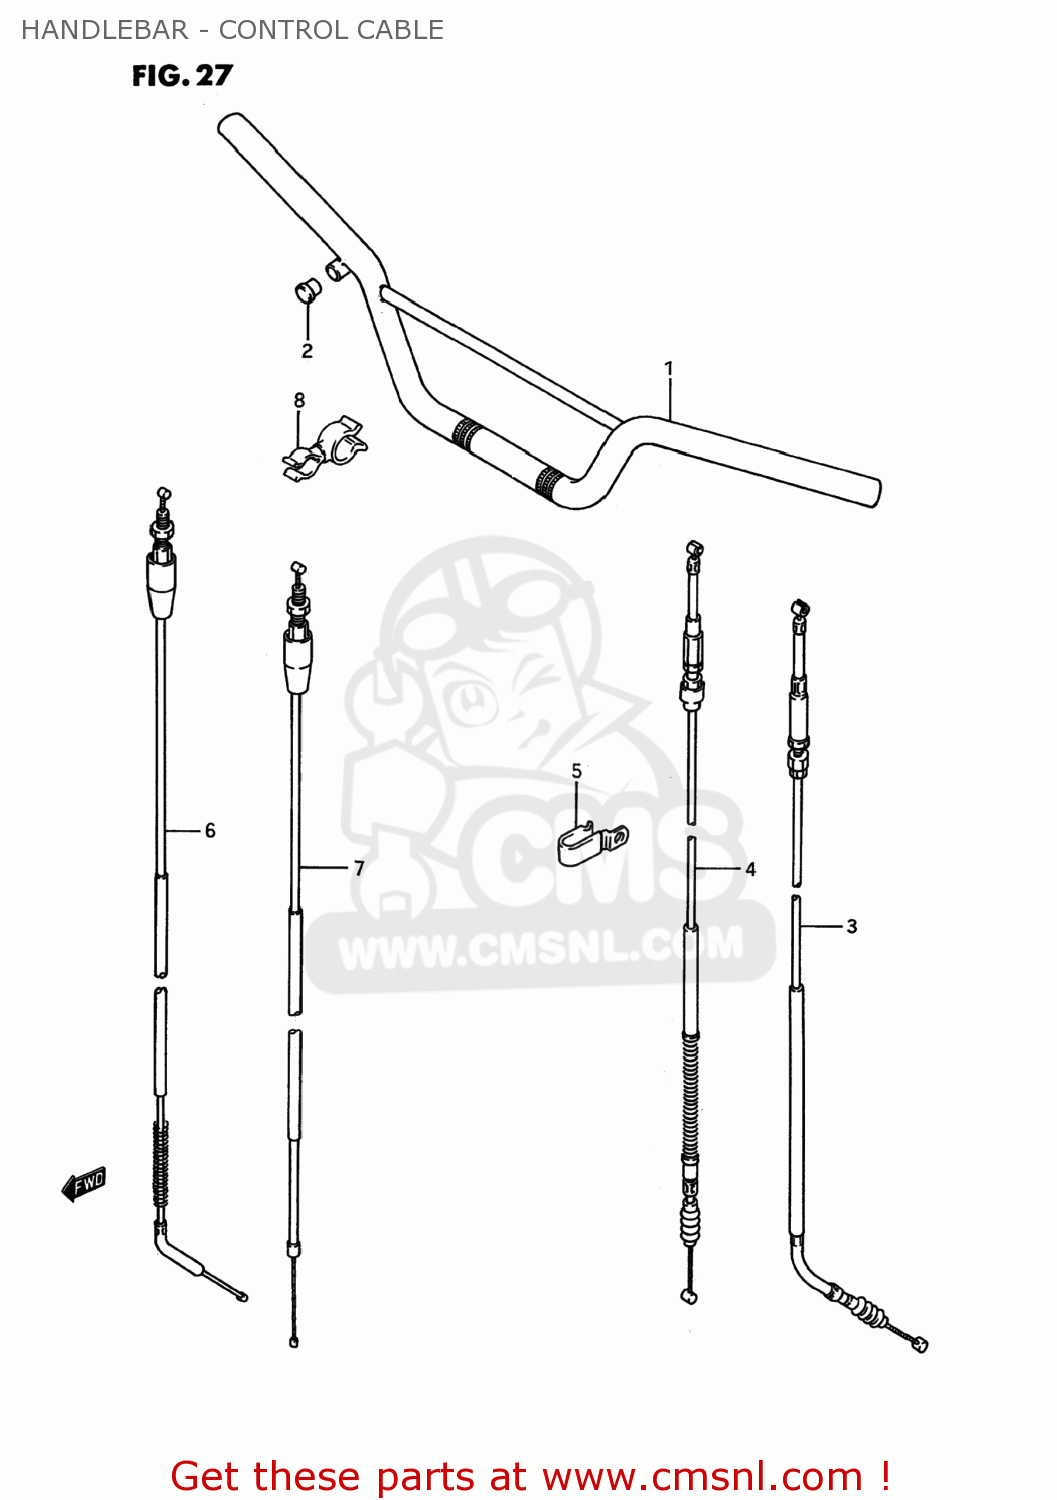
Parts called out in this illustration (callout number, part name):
1	HANDLEBAR
2	CAP(OD:14)
3	CABLE ASSY,CLUTCH
4	CABLE ASSY,CLUTCH
5	CLAMP
6	CABLE ASSEMBLY,THROTTLE
7	CABLE ASSEMBLY,THROTTLE
8	CLAMP
